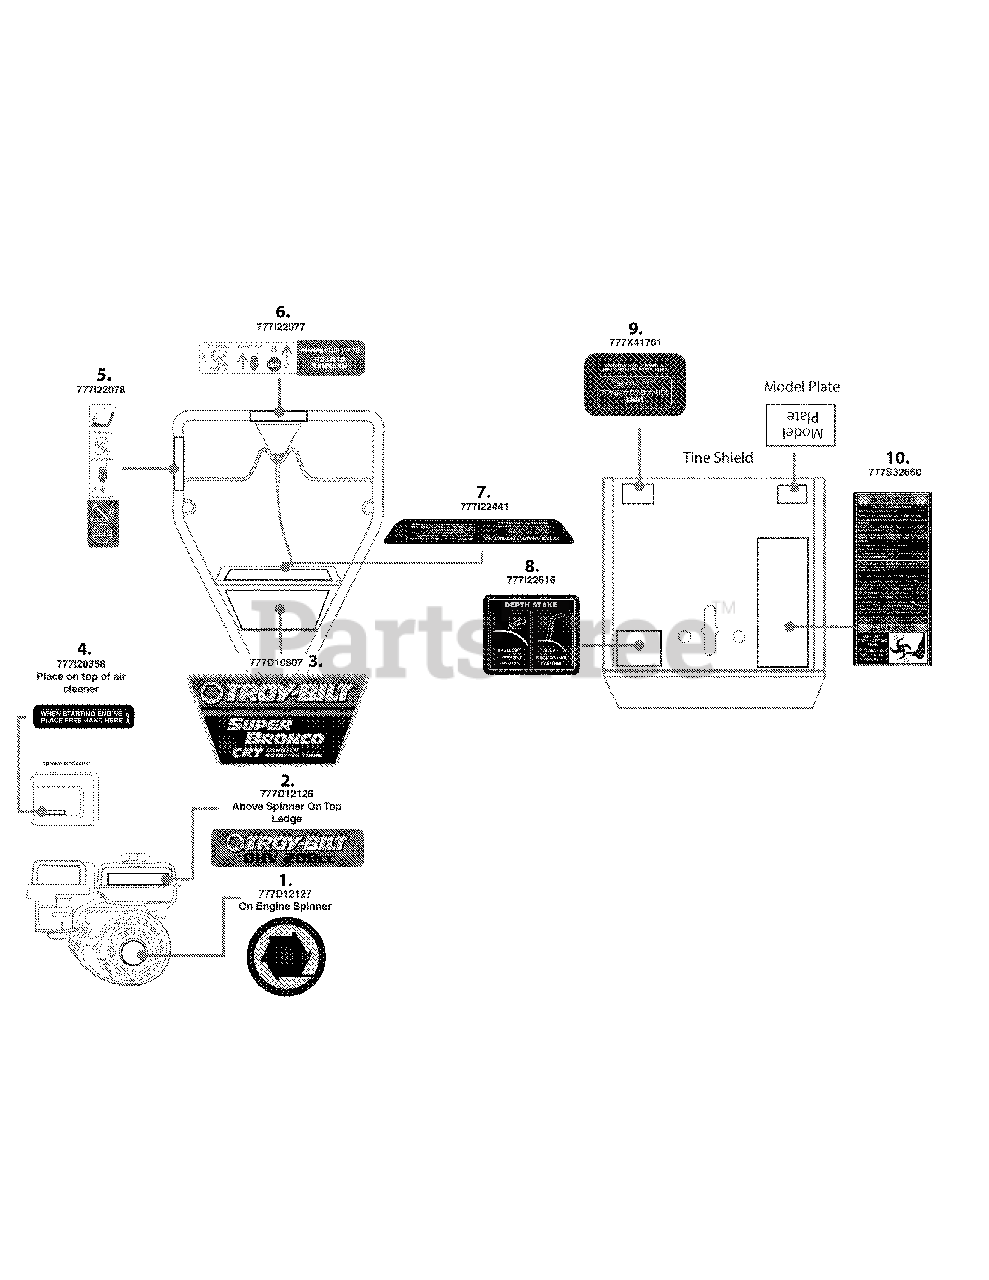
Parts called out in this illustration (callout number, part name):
1	LABEL-TILLER MTD ENGINE
2	LABEL-TILLER MTD ENGINE TROY
3	LABEL-TILLER HANDLE TROY
4	LABEL-PLACE HAND HERE
5	LABEL-TILLER
6	LABEL-TILLER
7	LABEL-HNDL PNL INST CRT SPR BRONCO
8	LABEL:TILLER TINE SHIELD DEPTH
10	LABEL:TILLER TINE SHIELD
